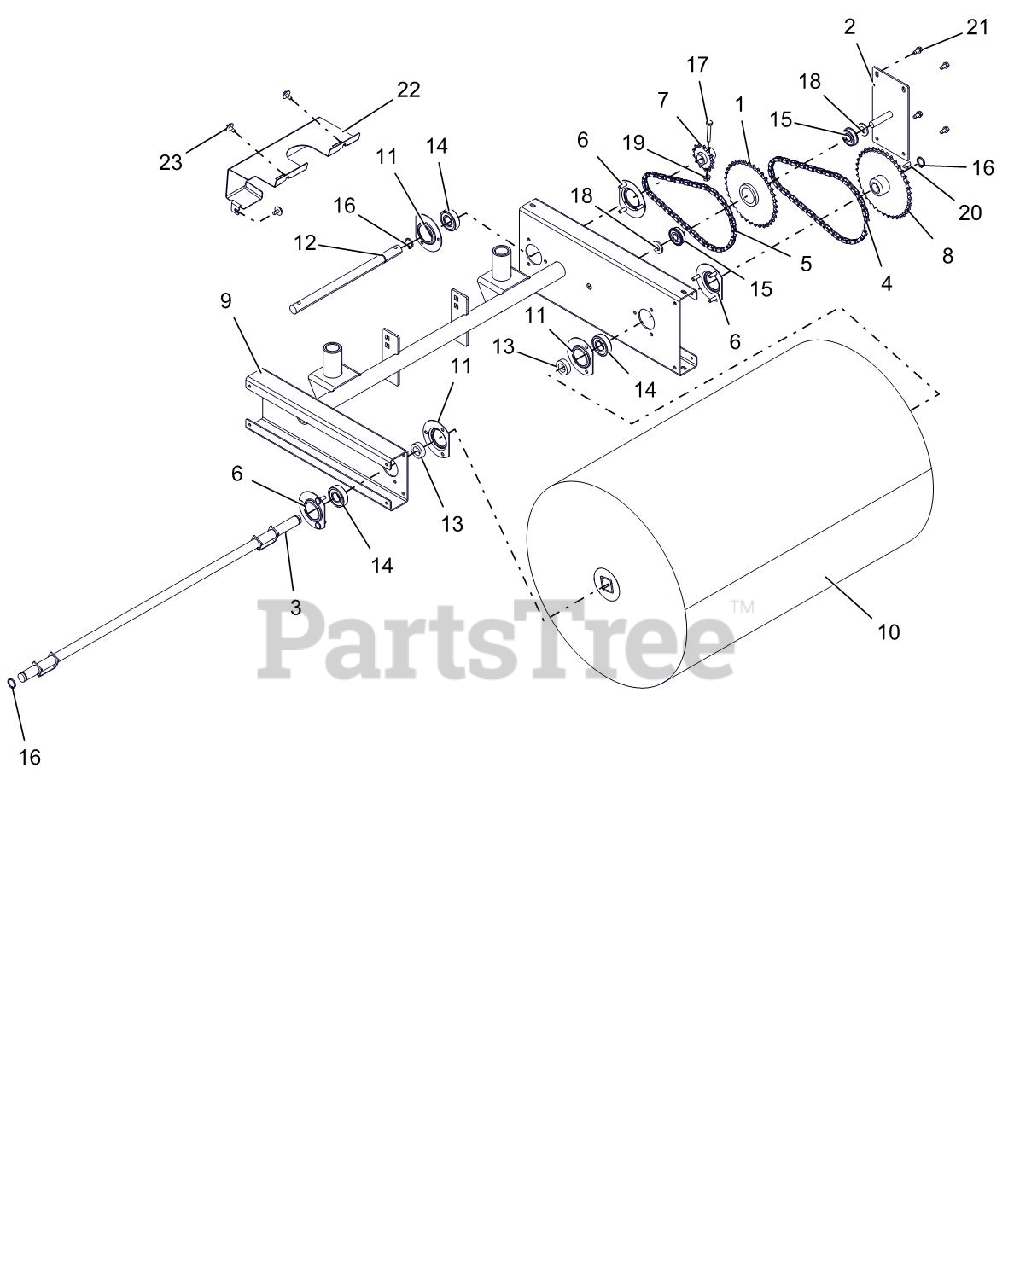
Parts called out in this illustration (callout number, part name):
1	SPROCKET, REDUCTION IDLER
2	PLATE, IDLER REDUCTION MOUNT
3	SHAFT, 28" BRUSH
4	CHAIN, #40-54 LINKS
5	CHAIN, #41-50 LINKS
6	BEARING FLANGE
7	SPROCKET, DRIVE
8	SPROCKET, DRIVEN
9	FRAME, POWER BROOM-DELUXE
10	BRUSH, 18"DIA X 28"WIDE
11	BEARING FLANGE
12	SHAFT, TRANSMISSION
13	SPACER .755X1.250X.370
14	BRG-BALL .750X1.750X.50
15	BRG-BALL .50X1.38X.438 SEALED
16	RG-RTNG-EXT .689X.078
17	@BLT-HEX .25-20X1.75 GR5 YWZC
18	WSHR-FL-STL .536X1.07X.109 YZ
19	@NUT-LK-TOP-FLG .25-20 YWZC
20	KEY-WDRF .188X.75X.313 SAE 9
21	SCR-TAP .25-20X.50 HWH TR YWZ
22	COVER, FRONT SHAFT - CE
23	SCR-TAP .25-20X.50 LGHWH TR YZ
